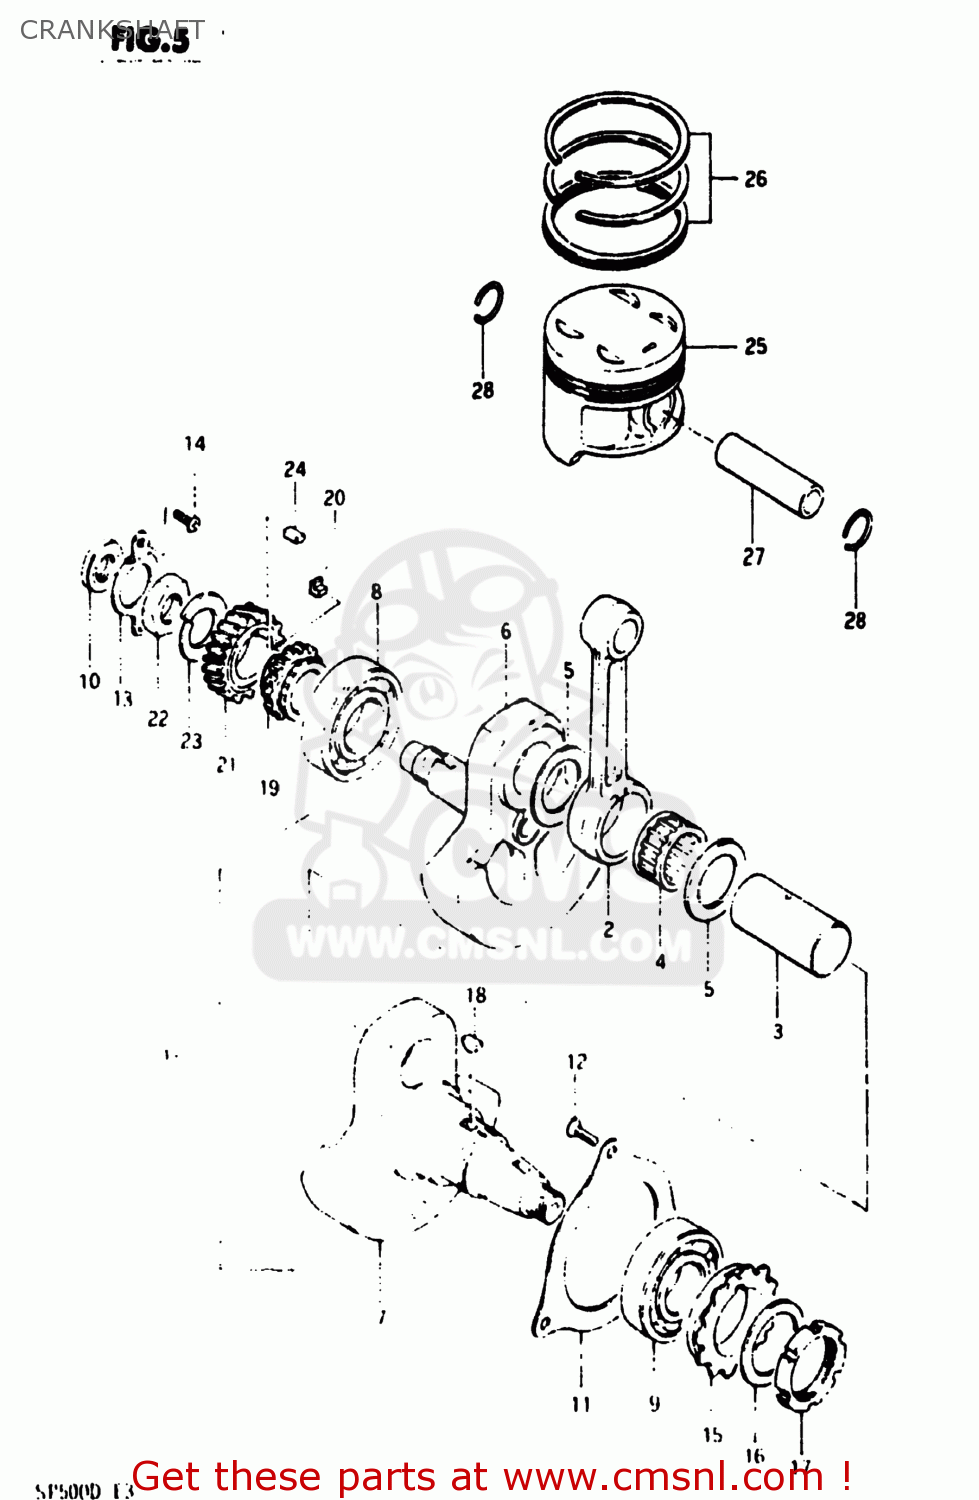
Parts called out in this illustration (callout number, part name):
1	CRANKSHAFT ASSEMBLY
2	ROD,CONNECTING
3	PIN,CRANK
4	BEARING(35X44X26)
5	WASHER(35X55X1)
6	CRANKSHAFT
7	CRANKSHAFT,LEFT
8	BEARING(35X80X21)
9	BEARING
10	SEAL,OIL(16X30X6)
11	RETAINER,CRANKSHAFT BEARING,L
12	SCREW
13	RETAINER,CRANKSHAFT BEARING,R
14	SCREW
15	SPROCKET,BALANCER DRIVE
16	WASHER
17	NUT,FLYWHEEL
18	KEY
19	SPROCKET,CAM CHAIN DRIVE
20	KEY,SPROCKET
21	GEAR,PRIMARY DRIVE
22	NUT (20MM)
23	WASHER
24	KEY
25	PISTON
26	RING SET,PISTON
27	PISTON PIN
28	RING,SNAP
